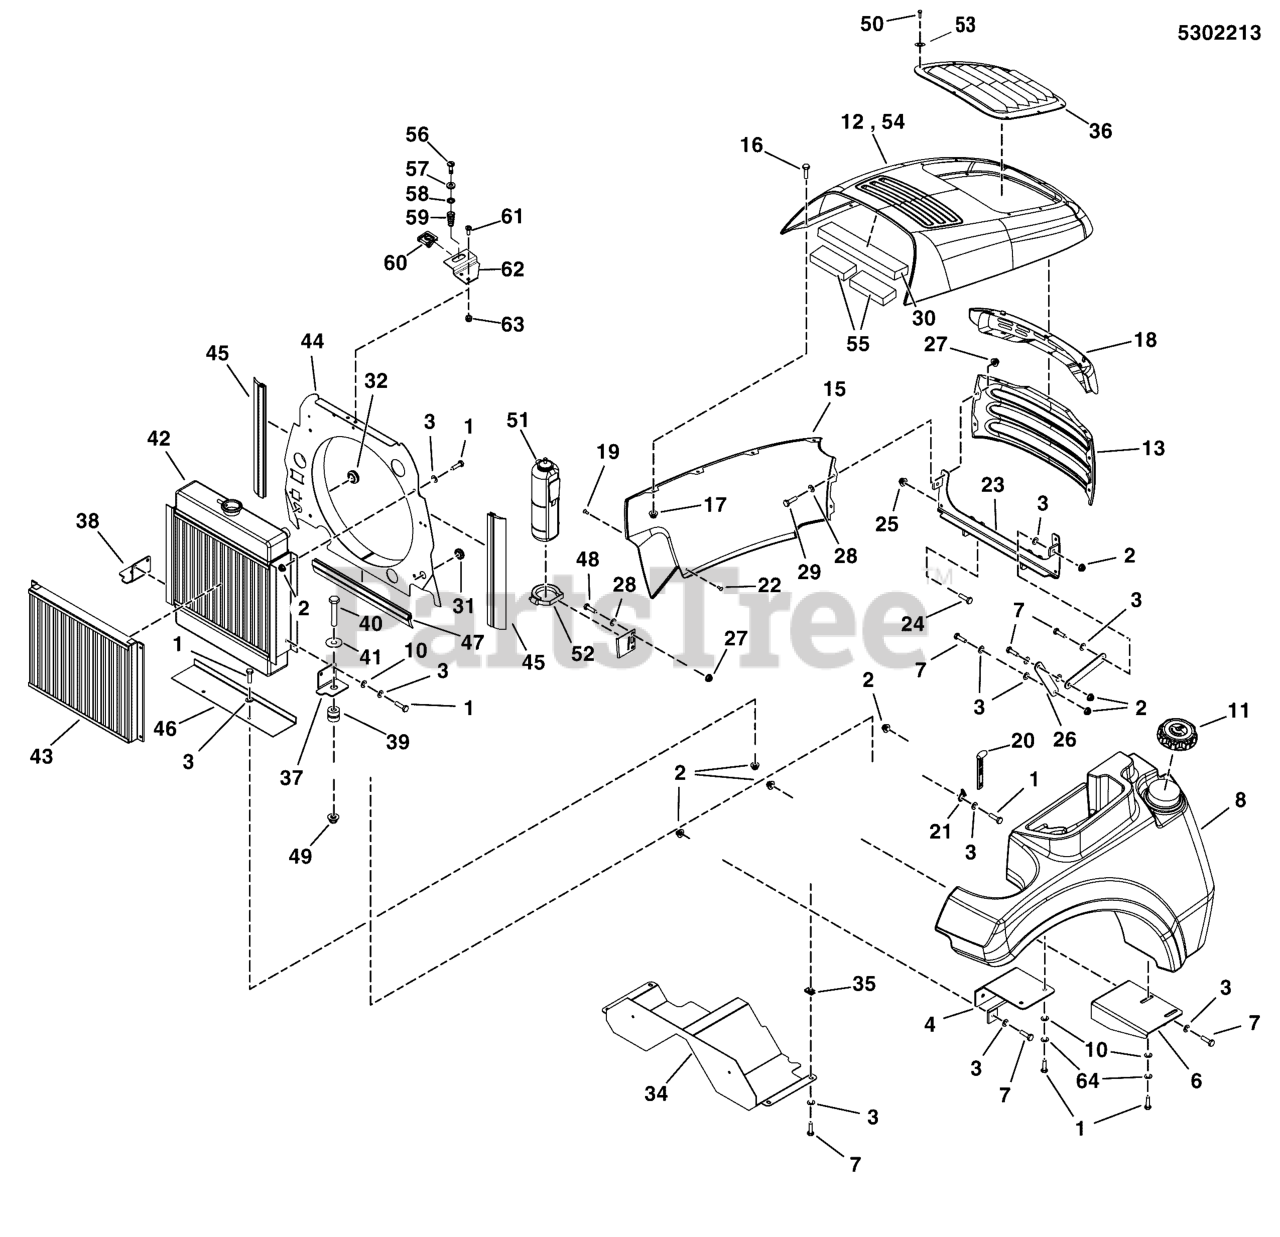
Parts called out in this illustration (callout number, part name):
1	BOLT, 5/16-18 X 3/4 GD5
2	NUT, 5/16-18 HEX NYLOCK FLANGE
3	WASHER, 5/16" SAE
4	MOUNT, FUEL TANK WELDMENT - FRONT - RED
6	WELD, TANK MOUNT, LH - RED
7	BOLT, 5/16-18 X 1 GD5 YZ
8	FUEL TANK, LH, S800XY
10	WASHER, 5/16 LOCK CZ
11	FUEL CAP, 3.5", NON VENTED, DIESEL (GRN)
12	HOOD, BOXED, F800X - FER RED
13	GRILLE, PERF METAL, OUT FRONT MOWER
15	PANEL-SIDE, 18GA LEGACY - PLAIN
16	SCREW-HEX WZ LOCK FLNG 1/4-20X0.625 BLK
17	NUT, 1/4-20 HEX SERR. FLANGE
18	MACHINED BLACK LENS, OUT FRONT MOWER
19	BINDING POST #8-32X.500 INT THR BLK
20	STRAP,HOOD,BLACK RUBBER
21	HOOK-.125DIA WIRE GR CAT STRAP YELLOW
22	SCREW-HEX SERR FLNG LK # 8-32X0.375 YEL
23	WELD, HOOD MOUNT - RED
24	BOLT, 3/8-16 X 3/8, 1/2 SHOULDER
25	NUT, 3/8-16 HEX SIDE LOCK
26	LINK, HOOD HINGE - RED
27	NUT, 1/4-20 HEX NYLOCK FLANGE
28	WASHER, 1/4 SAE
29	BOLT, 1/4-20 X 3/4 GD5 YZ
30	FOAM HOOD SEAL, OUT FRONT MOWER
31	GROMMET, 5/8 ID X 1/8 MATERIAL
32	GROMMET, 3/4
34	DEBRIS GUARD, PUMP - RED
35	BODY CLIP, 5/16-18-7GA MATERIAL
36	SCOOP, HOOD, OUTFRONT MOWER
37	BRACKET, RADIATOR MOUNT, LH - RED
38	BRACKET, RADIATOR MOUNT, RH - RED
39	MOUNT, ISO, BOTTOM, RAD 5000Z-DIESEL
40	BOLT, 3/8-16 X 2, GD5, CZ
41	WASHER, .390 X 1.50 X .109, YZ
42	RADIATOR, S800XY
43	SCREEN, FRONT, RAD, S800X YANMAR
44	WELD, FAN SHROUD, S800XY - RED
45	SEAL, WIPER, CLIP ON X 14" L
47	SEAL, WIPER, CLIP ON X 12-1/4" L
48	HHCS, 1/4-20 X 0.625, GR5, ZINC/CLEAR
49	NUT, 3/8-16 HEX NYLOCK FLANGE
50	RIVET-POP.188 .429L AL,AL STEM.37HD DIA
51	BOTTLE, COOLANT OVERFLOW (SV)
52	CLAMP, COOLANT OVERFLOW (SV)
53	WASHER, #10 SAE
54	WELD, HOOD, S/F800X CE - RED
55	FOAM, HOOD SEAL
56	DZUS, 1/4 TURN FASTENER, D8X16MM
57	DZUS, CUPPED WASHER
58	DZUS, RETAINER, PUSH-ON, SS
59	DZUS, EJECTOR SPRING
60	DZUS, RECEPTACLE, CLIP-ON, D8
61	SCREW- #10-24 X 1/2 ROUND PHILLIPS
62	MOUNT, HOOD FASTENER, S800X - RED
63	NUT, #10-24 HEX NYLON LOCK
64	WASHER, 5/16 F436 FLAT
